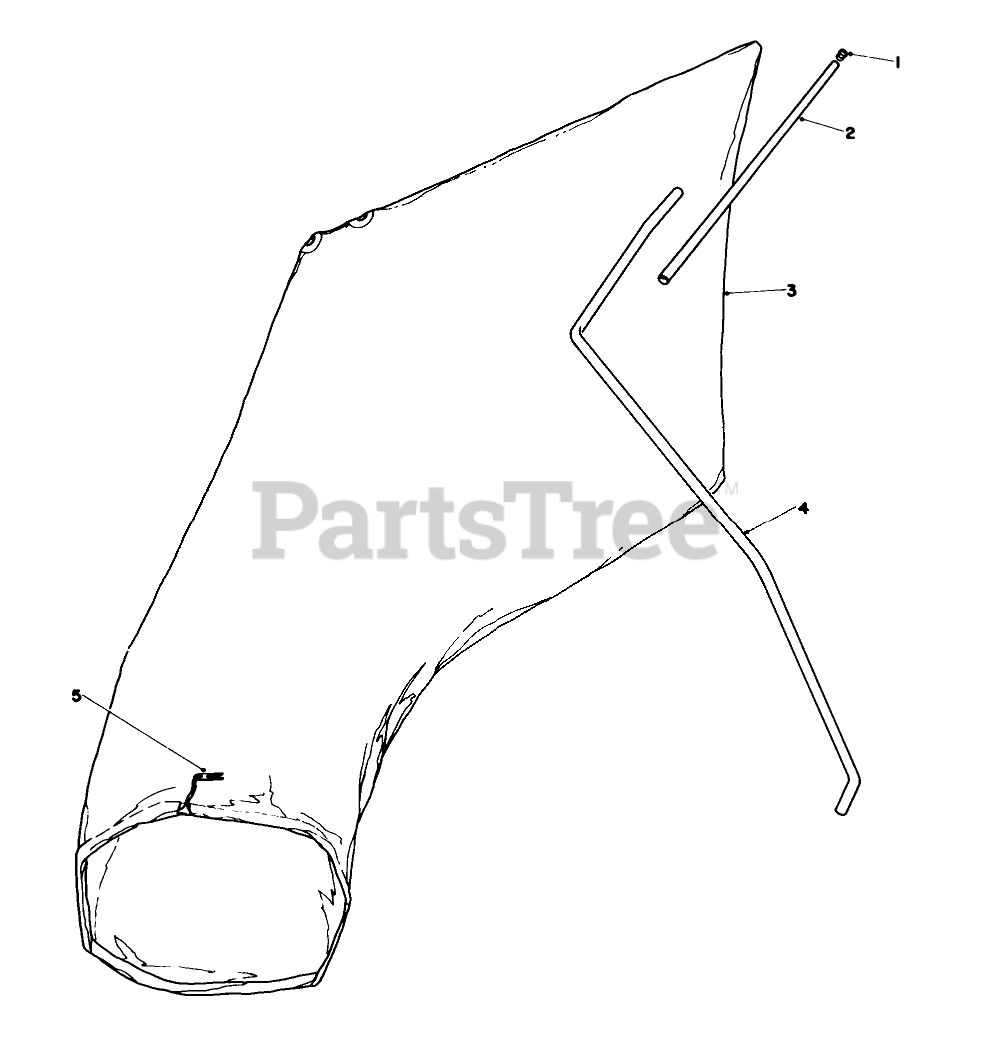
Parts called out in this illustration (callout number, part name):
2	BAG HANGER TUBE
3	(Incl. Ref. #5)
4	Hanger Rod
5	BAG CORD FASTENER
